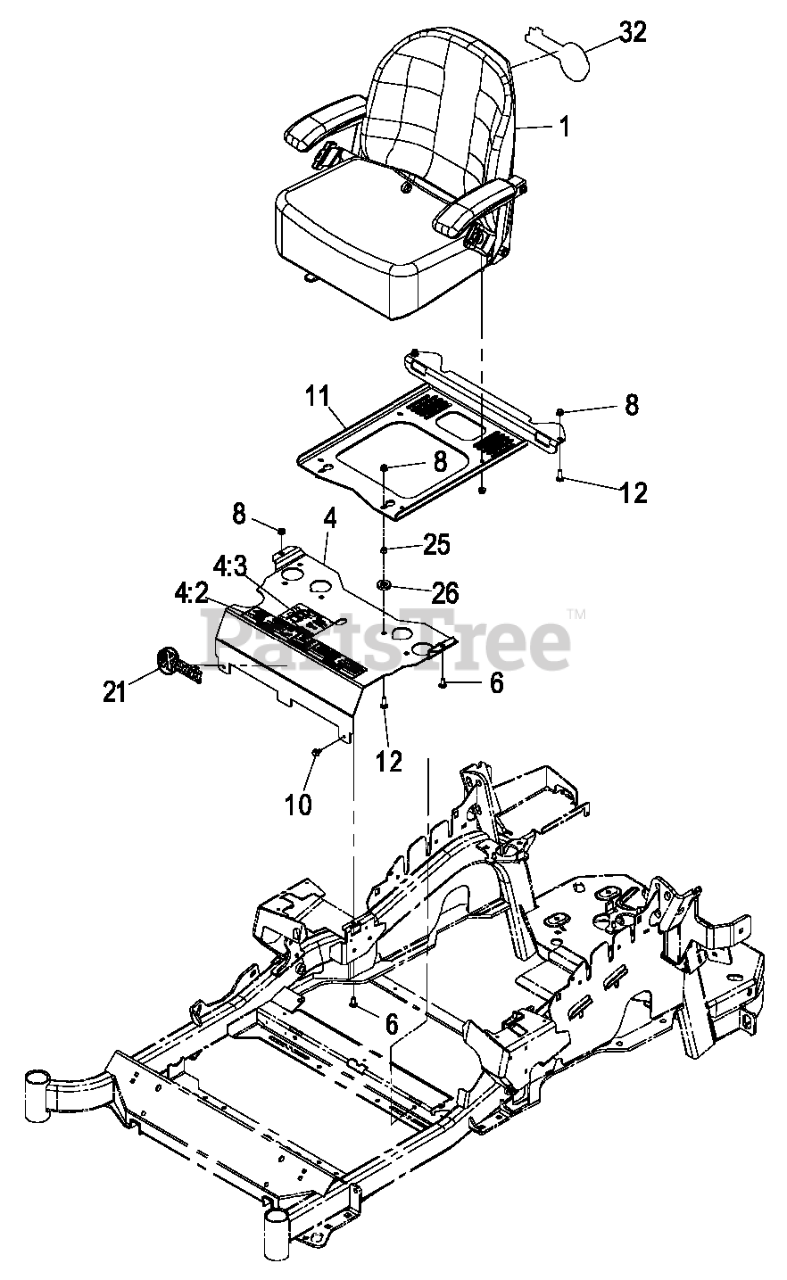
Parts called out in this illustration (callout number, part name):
4	MOUNT-SEAT
4:2	DECAL-CONSOLE
4:3	DECAL-SERVICE AID
6	SCREW-CARR
8	NUT-HF, NI
11	PLATE-SUPPORT, SEAT
12	SCREW-CARR
25	NUT-HEX
32	DECAL,EXMARK LOGO
